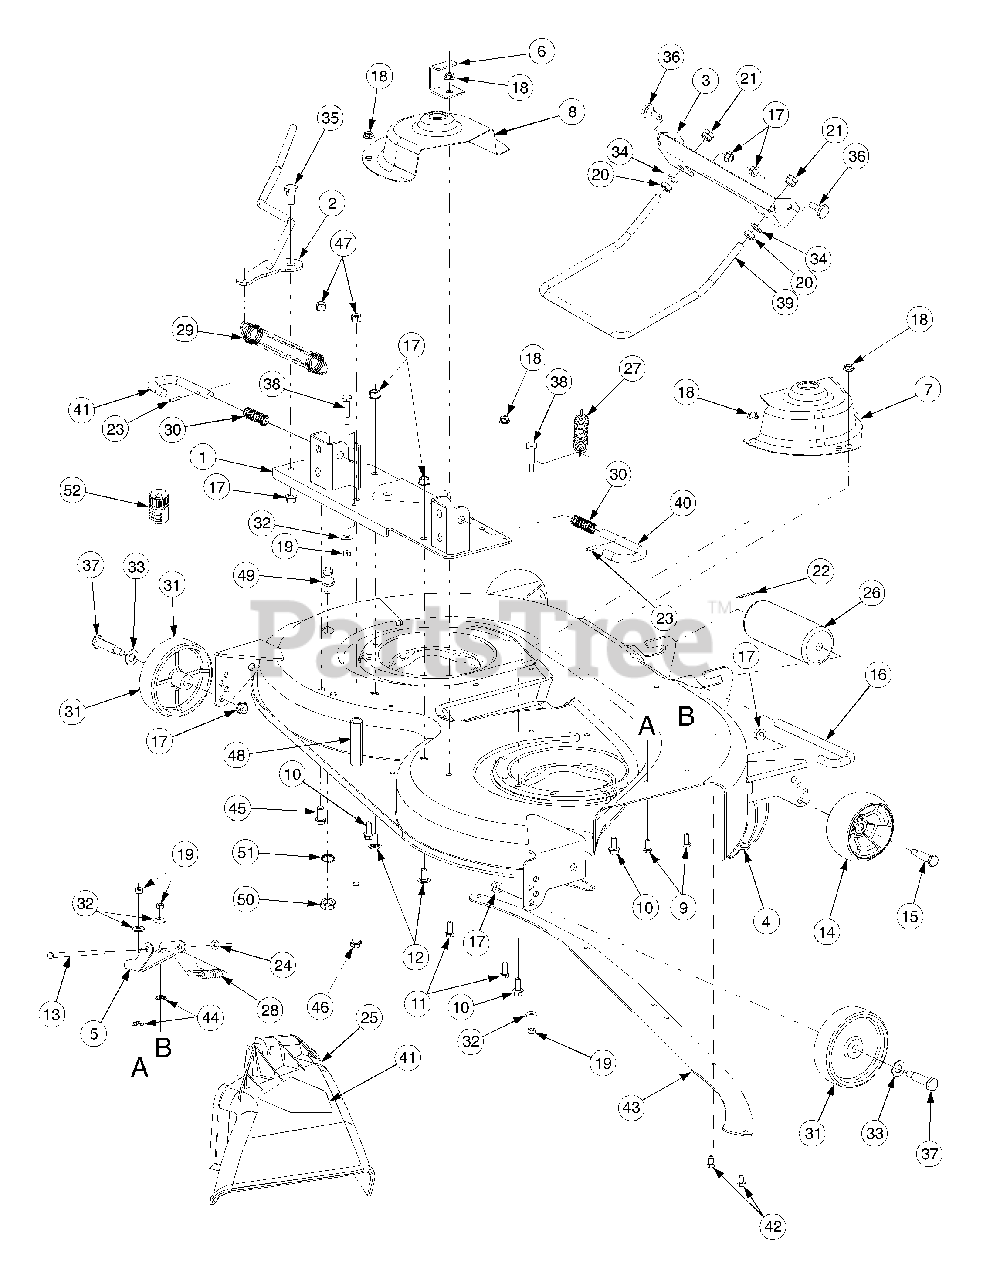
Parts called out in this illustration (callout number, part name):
5	Bracket, Hinge Mounting
9	Screw, Hex Cap, 1/4-20 x .62 GR5
10	Screw, Hx Wsh Hd Tapp, 5/16-18 x .75
11	Screw, Hex Cap, 5/16-18 x .75 GR5
12	Bolt, Carriage, 3/8-16 x .75
13	Pin, Hinge, .25 Dia x 6.75 Lg
14	Wheel, Deck w/Fitting
15	Bolt, Shoulder, 1/2 x 1.5 : 3/8-16
16	Pin, Roller, 1/2 Dia x 7.31 Lg
17	Nut, Hex Flange Lock, 3/8-16
18	Nut, Hex Flange Lock, 5/16-18 GR5
19	Nut, Hex, 1/4-20
20	Nut, Hex Jam, 1/2-13 GR5
21	Nut, Hex Insert Lock, 1/2-13
22	Pin, Cotter, 3/32 x 1.25
23	Pin, Spirol Spring, 3/16 x .75
24	Cap, Speed Nut
25	Deflector Assy Includes. #5, 13, 24,28, 45
27	Spring, Extension, .88 OD x 6.12
28	Spring, Torsion
29	Spring, Extension, 1.25 OD x 8.15
30	Spring, Compression
31	Wheel, Deck, 5 in. Dia
32	Washer, Bell, .265 x .75 x .062
33	Washer, Flat, .510 x 1.0 x .060
34	Washer, Lock, 1/2
35	Bolt, Shoulder, .498 Dia x .340 Lg
36	Bolt, Shoulder, .50 Dia x .434 Lg
37	Bolt, Shoulder, .498 Dia x 1.64 Lg
38	Bolt, Shoulder, .375 Dia x 1.16 Lg
39	Rod, Front Lift
40	Pin, Mower Support
41	Graphic, Danger
42	Screw, Self Tapping, 1/4-20 x .5
44	Nut, Push, 1/4
45	Screw, Hx Cap Lock, 3/8-24 x .75 GR5
46	Screw, Hex Cap, 3.8-24 x 3.75 GR5
47	Nut, Hex Insert Lock, 3/8-24
49	Nozzle, Deck Wash
50	Nut, Hex, M16-1.5
51	Washer, Lock
52	Adapter, Water Nozzle
